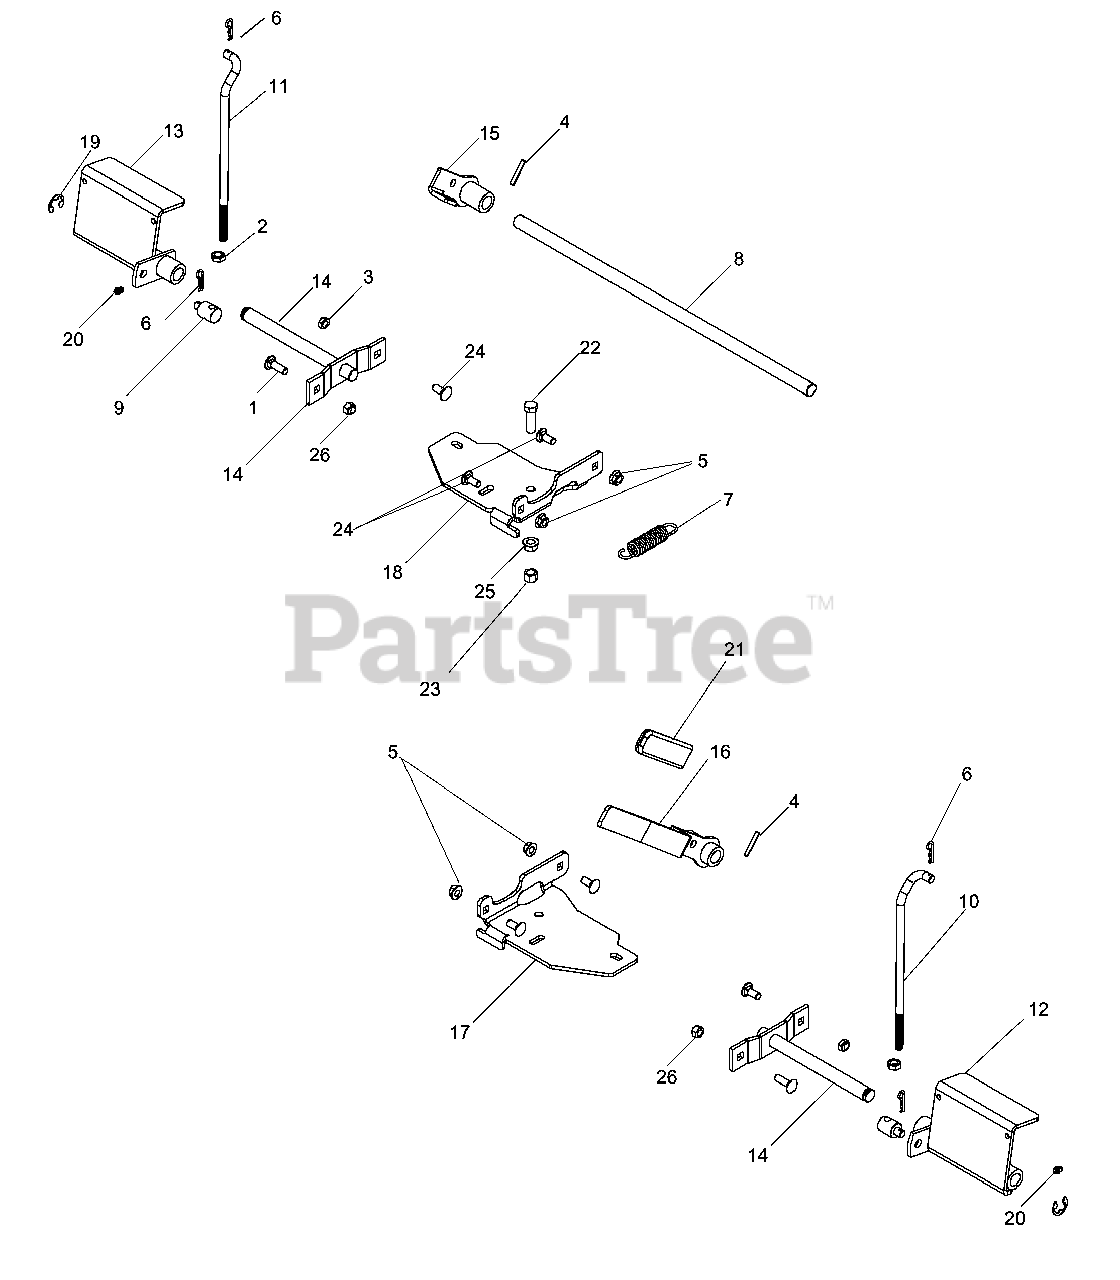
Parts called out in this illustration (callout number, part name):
1	RHSSNB 5/16C X 1.0
2	NUT 3/8-16 HEX JAM
3	5/16-18 THIN PROF NY
4	ROLL PIN 3/16 X 1-1/4
5	5/16-18 FLANGED L-NUT
6	COTTER HP .08 DIA X 1.19
7	SPRING - 3.50
8	SHAFT BRAKE
9	SWIVEL BRAKE
10	LH BRAKE LINK
11	RH BRAKE LINK
12	WLDT. BRAKE SHOE LH
13	WLDT. BRAKE SHOE RH
14	WLDT BRAKE PIVOT
15	BRAKE LINK DRILLED
16	BRAKE HANDLE DRILLED
17	BRKT. TANK MT. LH
18	BRKT. TANK MT. RH
19	RETAINING RING 5/8
20	GREASE ZERK-1/4"
21	GRIP BRAKE HANDLE
22	HCS 3/8C X 1 1/4 GR5
23	NUT 3/8-16 NYLOC
24	BOLT 5/16C X 3/4" CARRIAGE
25	NUT 3/8C WHIZ
26	NUT 5/16 NYLOC
